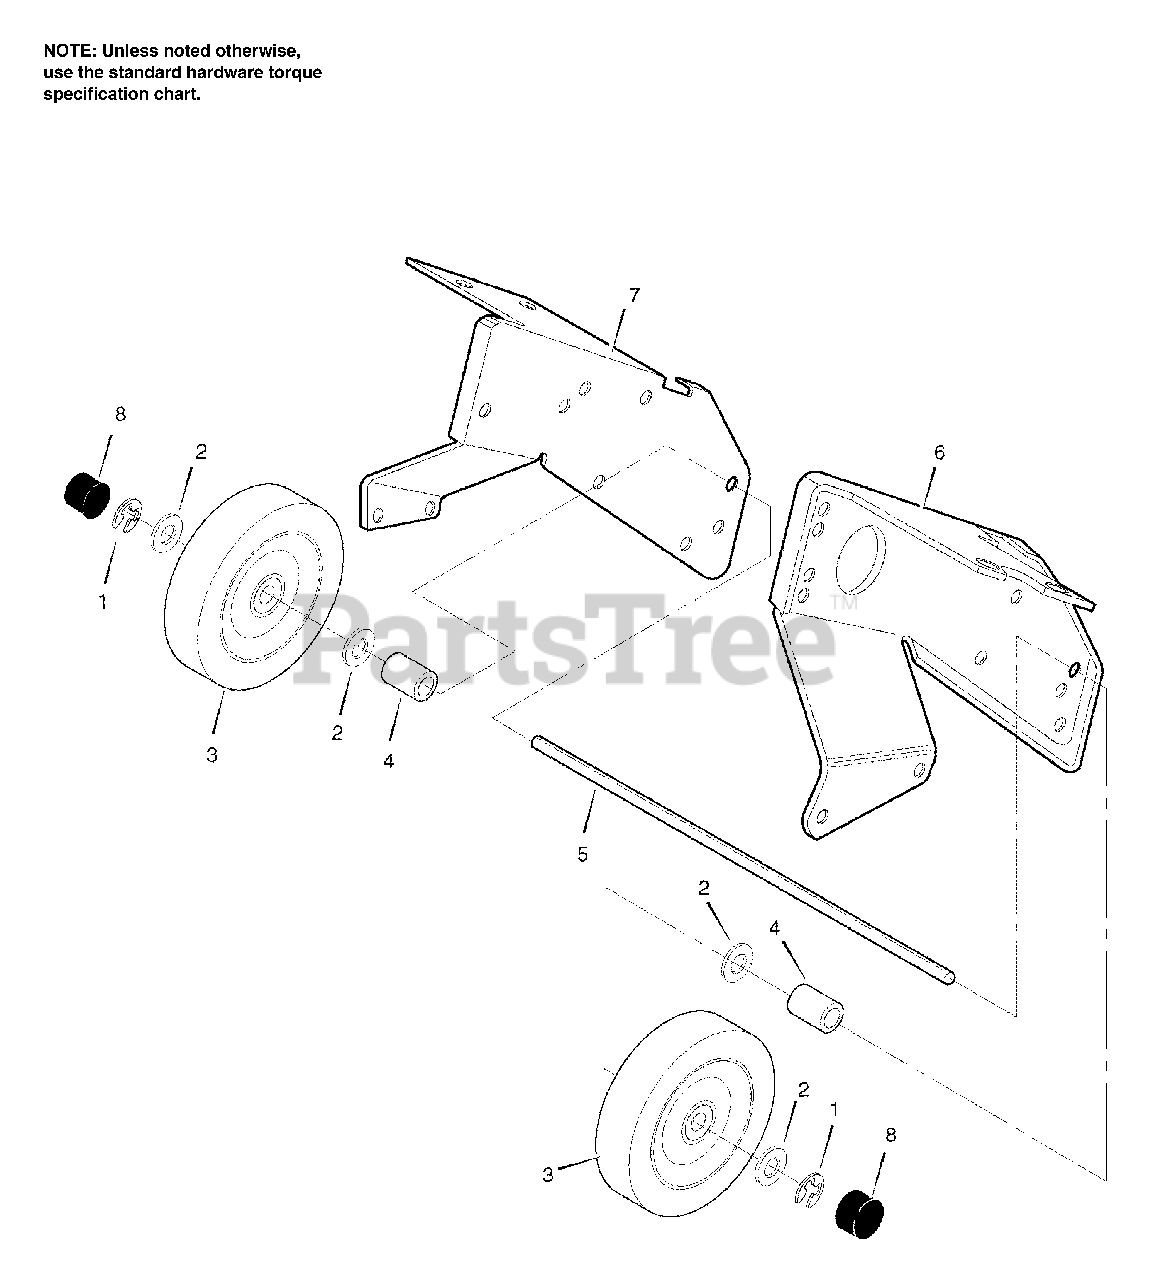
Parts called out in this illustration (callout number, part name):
1	RING, RET. E
2	WASHER, FLAT .406 x .81 x .07
3	WHEEL, 7.75" x 1.75"
4	SPACER, SLEEVE
5	AXLE SHAFT
6	PLATE, REAR MOUNT LH
7	PLATE, REAR MOUNT RH
